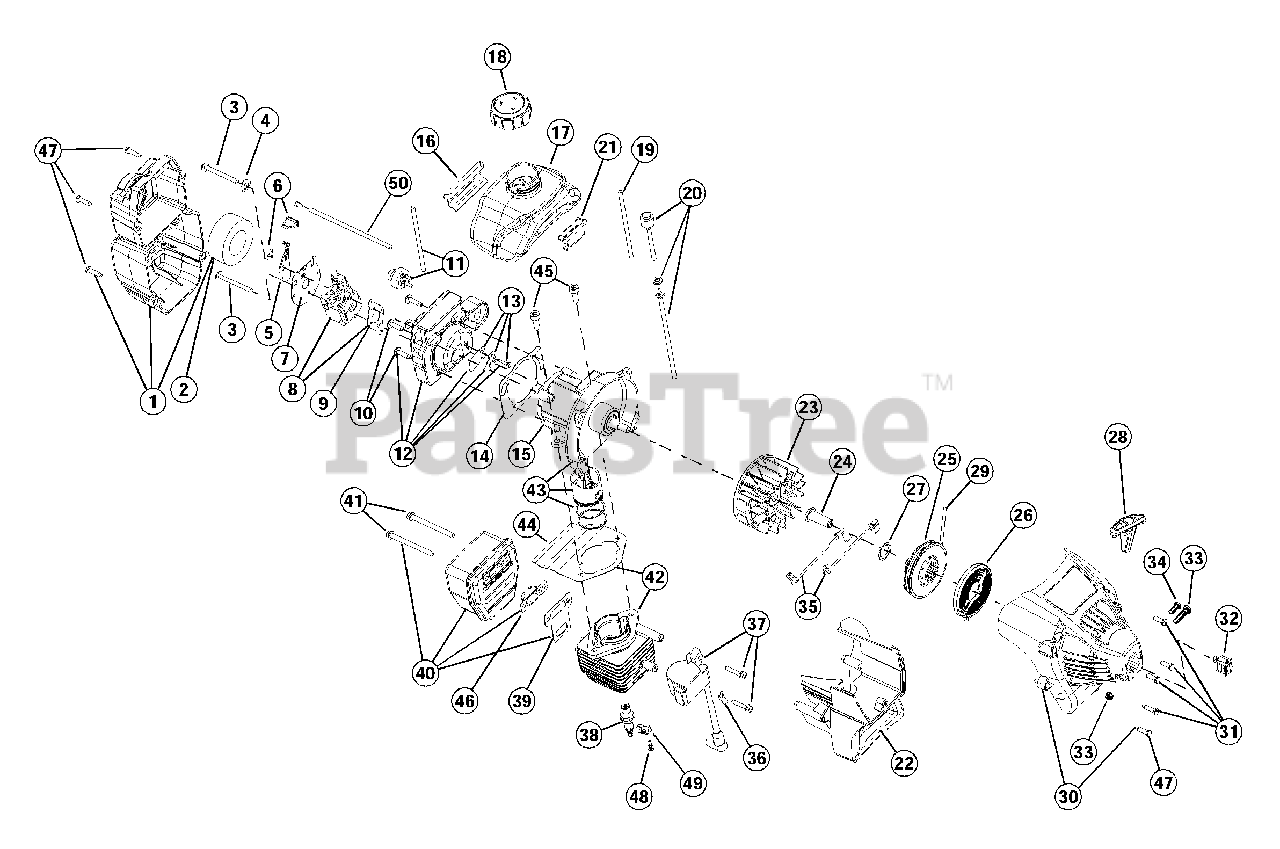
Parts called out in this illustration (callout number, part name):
1	Air Cleaner/Muffler Cover Assembly
2	Air Cleaner Filter
3	Carburetor Mounting Screws
4	Wavey Washer
5	Choke Lever Assembly
6	Choke Knob and Screw
7	Choke Lever and Plate
8	Carburetor Assembly
9	Carburetor Gasket
10	Carb Mount Screw
11	Primer and Hose Assembly
12	Carb Mount Assembly
13	Reed Assembly
14	Carburetor Mount Gasket
15	Crank Case Service Assembly
16	Rear Mounting Pad
17	Fuel Tank Assembly
18	Fuel Cap Assembly
19	Fuel Return Line
20	Fuel Line Assembly
21	Front Mounting Pad
22	Shroud Extension and Stand
23	Flywheel Assembly
25	Recoil Pulley
26	Recoil Spring
27	Pulley Retainer
28	Pull Handle
30	Starter Housing Assembly
31	Housing Screws
32	On/Off Switch
33	Clamping Screw & Nut
34	Anti-Rotation Screw
35	Wire Leads
36	Ground Tab
37	Module Assembly
38	Spark Plug
39	Exhaust Gasket
40	Muffler Assembly
41	Muffler Mounting Bolt
42	Cylinder Assembly
43	Piston and Rod Assembly w/Rings
44	Cylinder Gasket
45	Cylinder Bolt
46	Spark Arrestor Screen
47	Cover Screws
48	Compression Relief Valve
49	Compression Relief Valve Spring
50	Compression Relief Valve Cable
